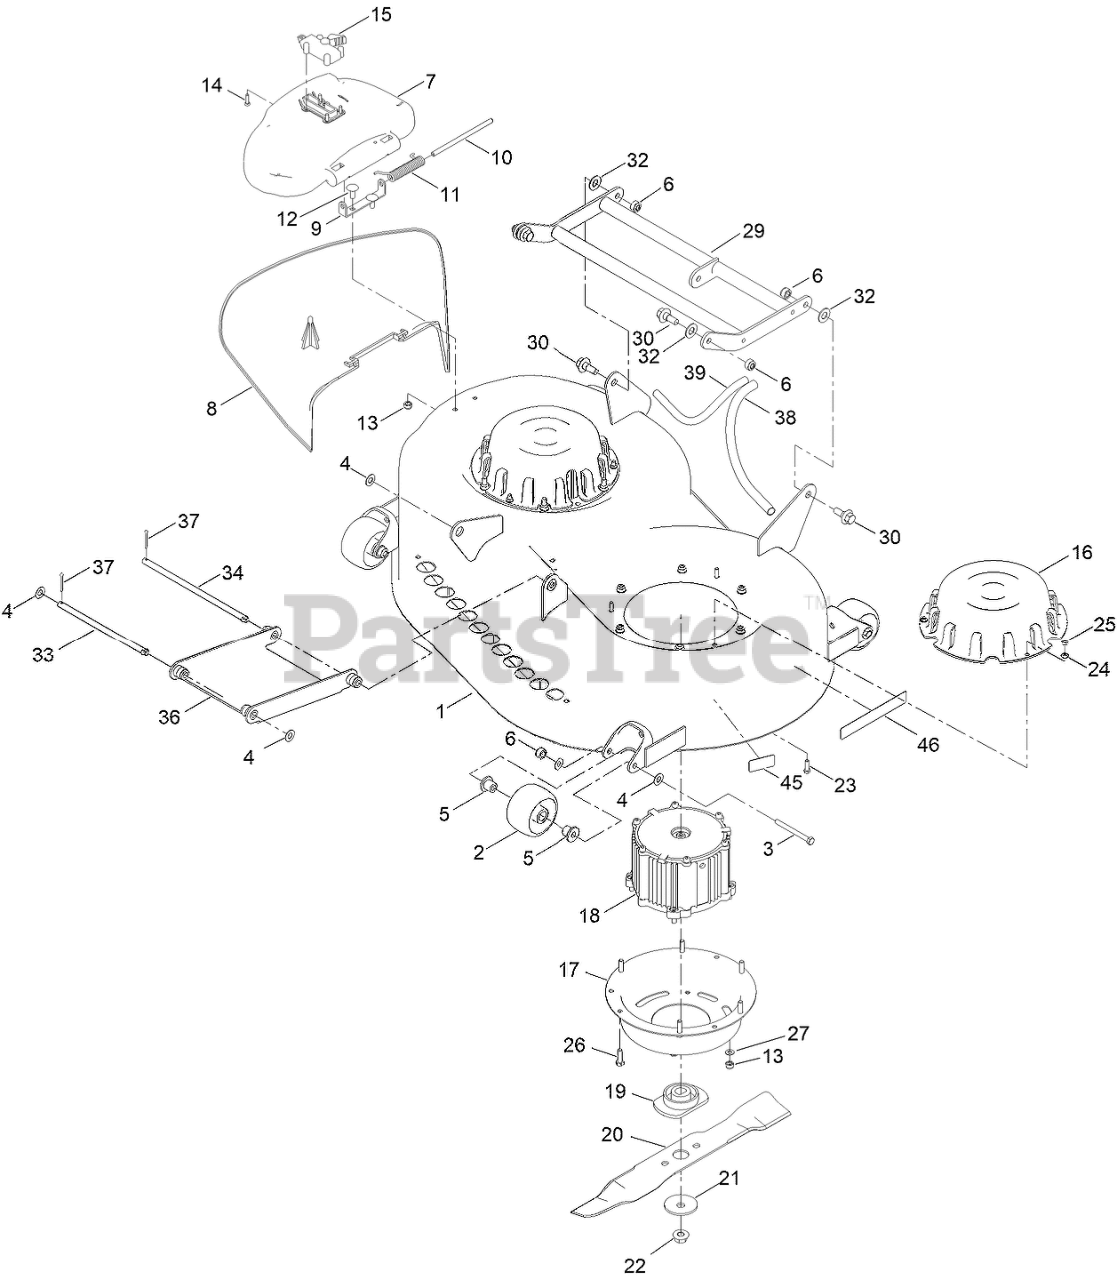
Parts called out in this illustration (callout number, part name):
1	WELDED DECK ASM
2	WHEEL, DECK
3	BOLT-HH
4	WASHER-PLAIN
5	INSERT, DECK WHEEL
6	NUT-HEX, NI
7	COVER, DECK CHUTE
8	CHUTE, DECK
9	BRACKET, DISCHARGE FLAP
10	ROD, DISCHARGE FLAP
11	SPRING, DISCHARGE FLAP
12	BOLT-CARRIAGE
13	NUT-NYLOC
15	DECK CHUTE CLIP, ASM
16	TOP COVER, DECK MOTOR
17	BOTTOM COVER, DECK MOTOR
18	MOTOR, DECK
19	HUB, BLADE MOTOR
20	BLADE, DECK
21	WASHER, BLADE
22	NUT, BLADE
23	SCREW-HH
24	WASHER
25	NUT-LOCK
26	SCREW-HH
27	WASHER-PLAIN
29	REAR HOC LIFTING ASM
30	FLANGE BOLT
32	WASHER-PLAIN
33	ROD, FRONT DECK MOUTNING (SHORT)
34	ROD, FRONT DECK MOUTNING
36	MOUNTING BRACKET ASM, DECK
38	COVER, WIRES
39	COVER, WIRES
45	DECAL - NO SPRAY
46	DECAL - DECK WARNING
